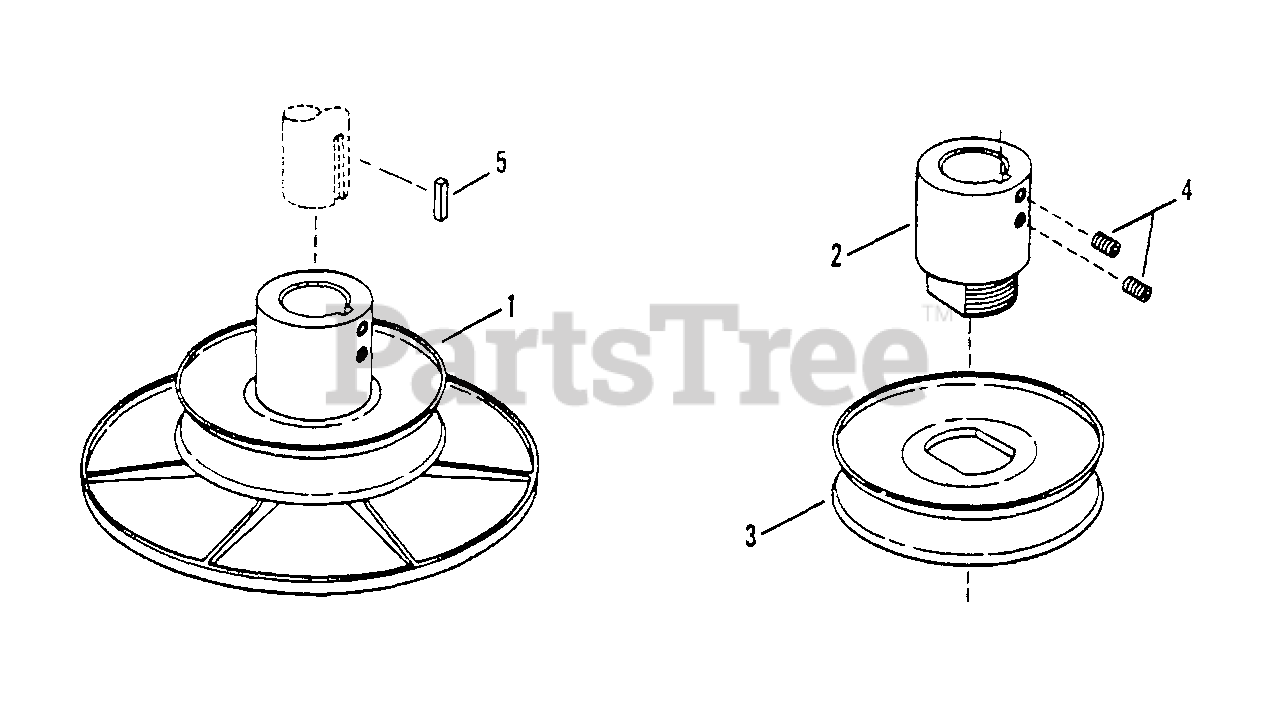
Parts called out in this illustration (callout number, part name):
1	ASSEMBLY, 4" O.D. Drive Disc (33" Models)
3	PULLEY, Drive (25" & 28" Models)
4	SCREW, 3/8-16 x 3/8" Set
5	KEY, 1/4 Square x 2"
